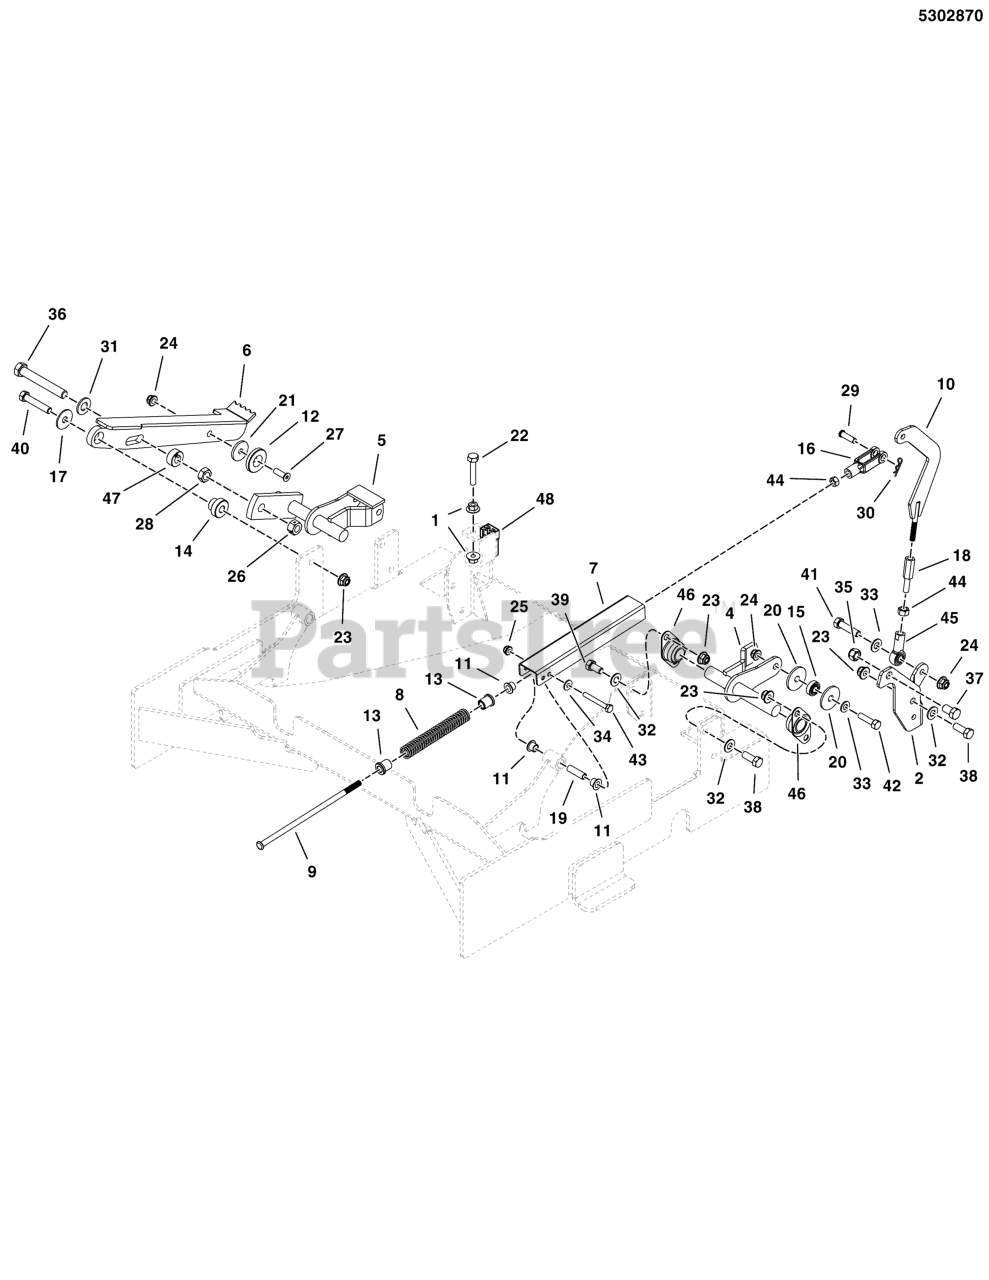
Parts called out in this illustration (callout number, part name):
1	NUT, .31-24 HEX FLG SERRATED LK
2	PLATE, CONTROL MOUNT, LH - RED
4	WELD, CONTROL SHAFT, SW30, LH - RED
5	WELD, CONTROL SHAFT, SW30, RH - RED
6	WELD, FOOT PEDAL, SW30 - RED
7	WELD, SPRING HOUSING, SW30 - RED
8	SPRING, COMP. .61 ID X .775 X 7.0 LG,.08
9	BOLT, 5/16-24 X 8, GD8, CZ
10	WELD, CONTROL RAMP, WB
11	BUSHING, .38ID X .47 OD X .38L, FL
12	SPACER, .34 X 1.54 X .25 - UHMW
13	BUSHING, .38 X .75 X .75, PLASTIC
14	SPACER, .38 X 1.13 X .781 STEP, CZ
15	BEARING, .375" ID X .875" OD X .341" THK
16	CLEVIS, 5/16-24, STEEL, CLEAR ZINC
17	WASHER, 3/8" Fender
18	ADJUSTER, ROD LINKAGE 5/16-24
19	SPACER, .26 X .38 X 1.250, YZ
20	WASHER, .390 X 1.50 X .109, YZ
21	WASHER, .34 X 1.25 X 10 GA
22	BOLT, 5/16-24 X 1-3/4, FULL THRD, GD5 YZ
23	NUT, 3/8 - 16 HEX NYLOCK FLANGE
24	NUT, 5/16-18 HEX NYLOCK FLANGE NUT
25	NUT, 1/4-20 Hex Nylock Flange
26	NUT, 1/2-13 Hex Side Lock
27	SCREW, 5/16-18 X 1, PHILLIPS HD, BZ
28	NUT, Hex, Jam, 1/2-13
29	PIN, CLEVIS, 5/16 X 1, PLATED
30	COTTER PIN, 5/32 X 3/4
31	WASHER, 1/2 SAE
32	WASHER, 3/8 SAE
33	WASHER, 5/16" SAE
34	WASHER, 1/4 SAE
35	NUT, 7/16-14 HEX TOP LOCK
36	BOLT, 1/2-13 X 3-1/4, HEX HD, GD5, CZ (SV)
37	BOLT, 7/16-14 X 3/4, GD 5 YZ
38	BOLT, 3/8-16 X 1" GD5 CZ
39	BOLT, 3/8-16 X 3/4" GD5 CZ
40	BOLT, 3/8-16 X 2, GD5, CZ
41	BOLT, 5/16-18 X 1-1/2" GD5 YZ
42	BOLT, 3/8-16 X 1-1/4" GD5 CZ
43	BOLT, 1/4-20 X 2", GD5
44	NUT, Hex Jam, 5/16-24
45	BALL JOINT 5/16-24 RH FEMALE BRONZE RACE
46	BEARING, BRONZE FLANGE, 3/4"
47	COLLAR, 1/2 SET (1/2 SPLIT COLLAR IN MODEL)
48	SWITCH, PLUNGER, N.O./N.C.
